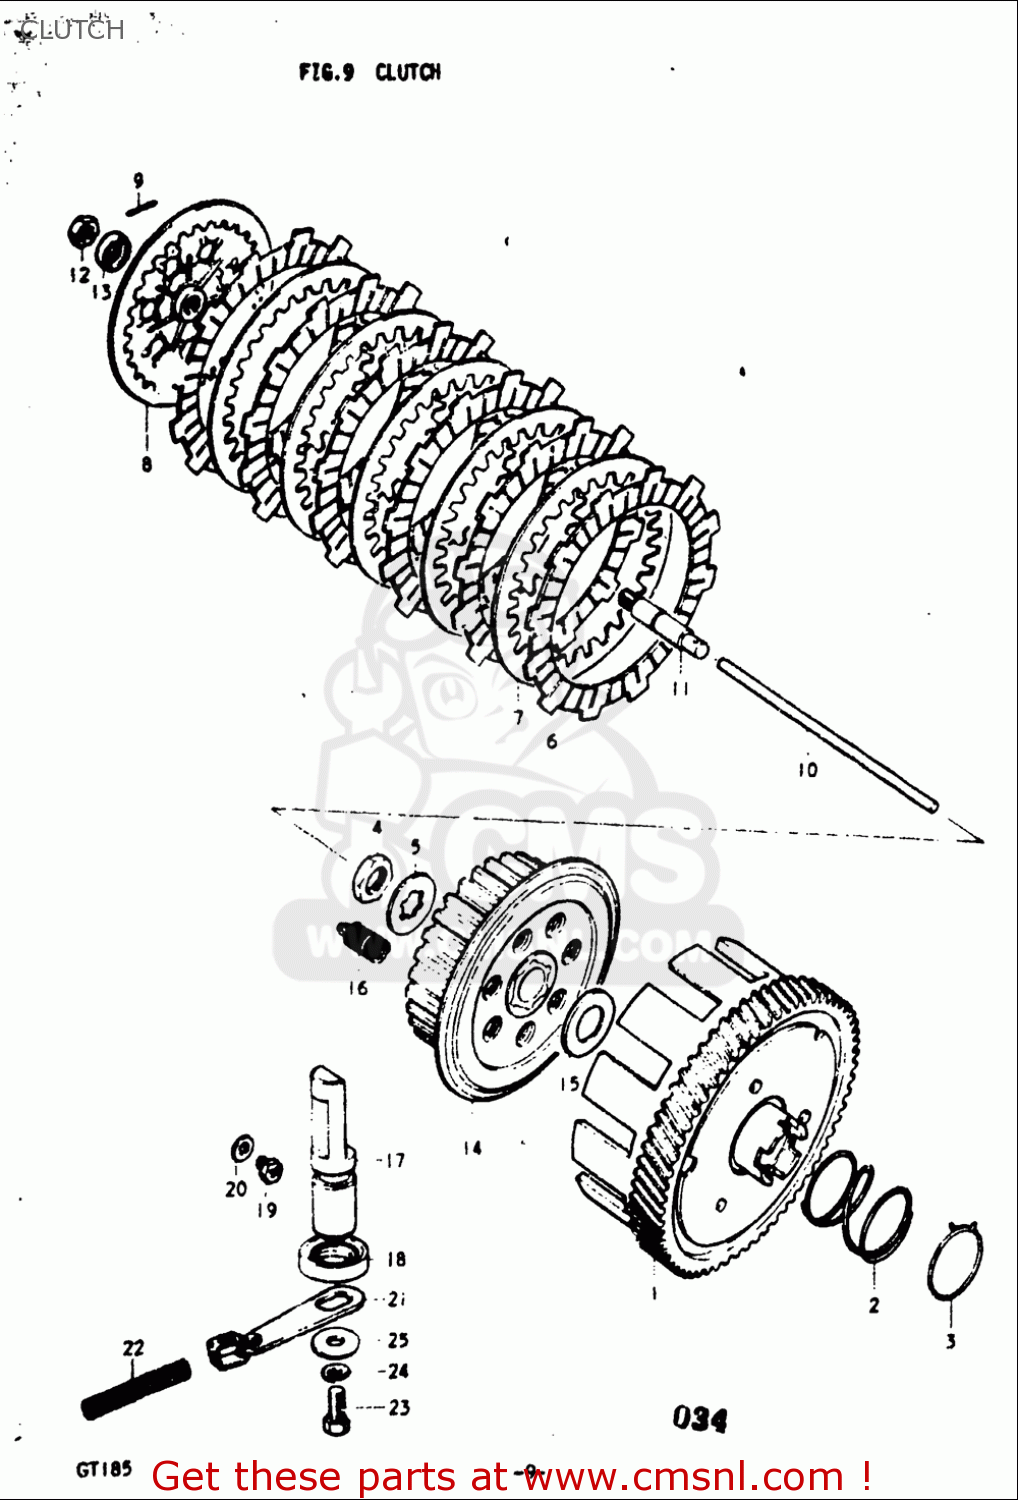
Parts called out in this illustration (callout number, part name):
2	SPRING
3	SPRING
4	NUT
5	WASHER,LOCK
6	PLATE,CLUTCH DRIVE(T:3.0) (NAS)
7	PLATE,CLUTCH DRIVEN (NAS)
9	PIN(2.5X19.8)
10	ROD, CLUTCH PUSH B
12	NUT
13	SEAL,OIL(8X17X5)
15	WASHER
16	SPRING
18	OIL SEAL (22X30X8)
19	BOLT
20	WASHER
22	SPRING
23	BOLT
24	WASHER,LOCK
25	WASHER(8.5X24X1.6)
